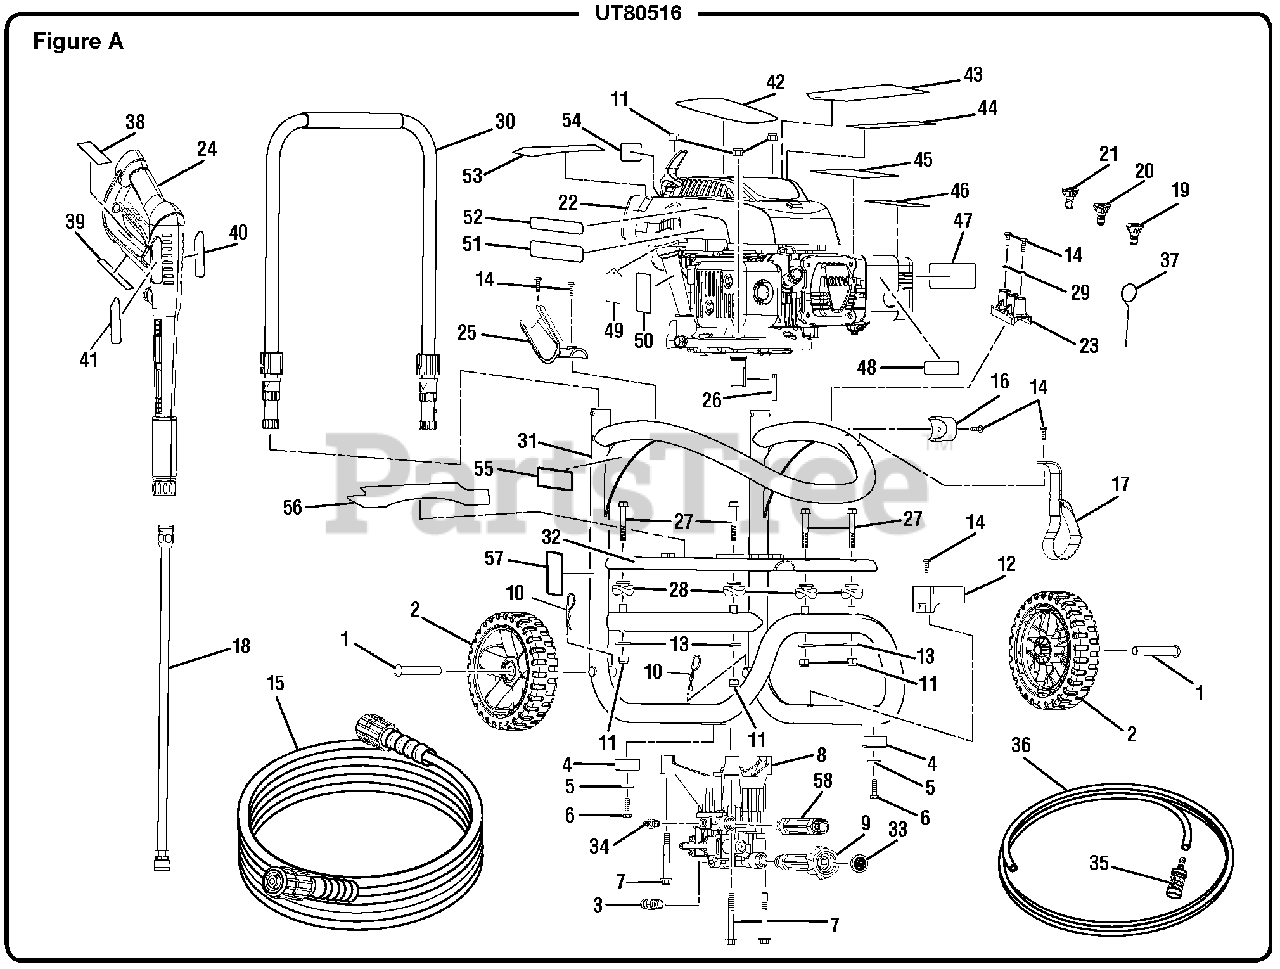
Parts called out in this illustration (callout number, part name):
3	Thermal Release Valve
5	Washer (1/4 in.)
6	Bolt (1/4-20, Hex Hd.)
7	Bolt (M8 x 70 mm, Hex Hd.)
9	Inlet Tube
10	Hitch Pin
11	Lock Nut (M8)
12	Lower Wand Holder
13	Washer (5/16 in.)
14	Screw (12-14)
15	Hose (25 ft.)
16	Upper Wand Holder
17	Strap
18	Lower Wand Assembly
19	Nozzle, 25deg
20	Nozzle, 0deg
21	Soap Nozzle
22	140cc Engine
23	Nozzle Holder
24	Spray Wand Assembly
25	Spray Wand Holder
26	Output Shaft Key
27	Bolt (M8 x 52 mm, Hex Hd.).
29	Washer (OD11 x ID5.5 x 1.2t).
30	Handle Assembly
32	Engine Mounting Plate
33	Inlet Tube Filter Screen
34	Detergent Suction Kit
35	Chemical Siphon Filter
36	Chemical Siphon Tube
37	Nozzle Cleaning Tool
38	Warning Label
39	Trigger Handle Spec Label
40	Wand Warning Label
41	Wand Logo Label
42	Performance Label (Engine)
43	Warning Hangtag
44	No Oil Label
45	Combustion Label
46	Information Label
47	Release Water Label
48	Primer Bulb Label
49	Add Oil Hangtag
50	Add Oil Label
51	Hot Surface Label
52	EMC Label
53	Quick Start Label
54	E-85 Label
55	Lubricant Label
56	Danger Label
57	Data Label
58	Outlet Tube
